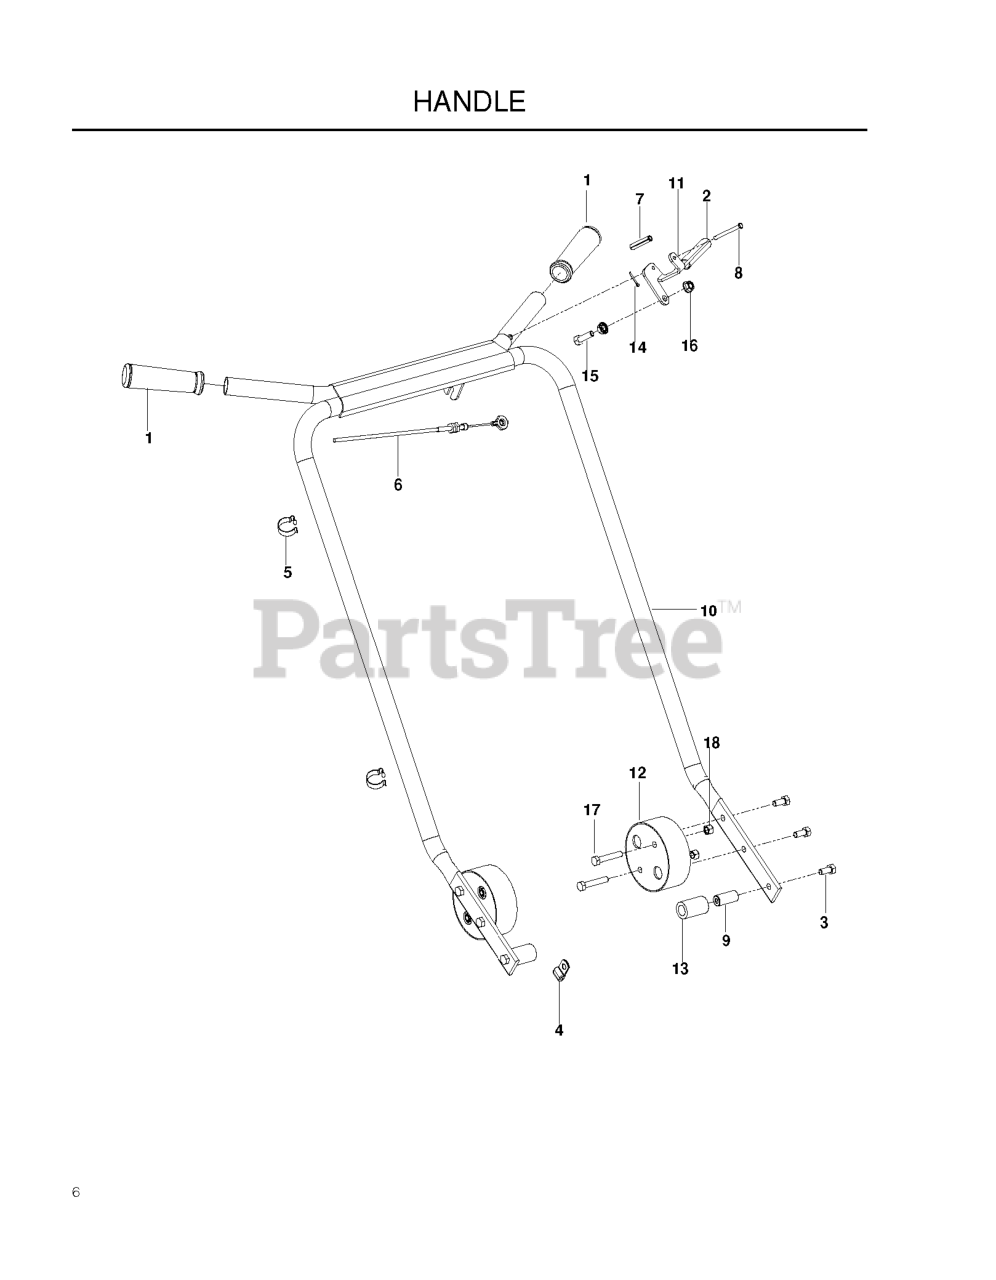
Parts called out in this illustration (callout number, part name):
1	GRIP, HANDLE 1" ID BLACK
3	HCS M8-1.25 X 22MM GR 8.8 ZD
4	DOUBLE TUBE CLAMP
5	CLIP - CABLE
6	CABLE - PULL
7	5/16" DIA ROLL PIN X 1.5
8	PIN, CLEVIS
10	HANDLE - GREY
11	LEVER - THROTTLE, ORANGE
12	MOUNT, VIBRATION
13	BUSHING, POLYURETHANE
14	COTTER PIN 3/32 X 3/4
15	HCS 5/16C X 1
16	NUT 5/16C WHIZ
17	HCS 5/16C X 1 3/4
18	NUT 5/16 NYLOC
